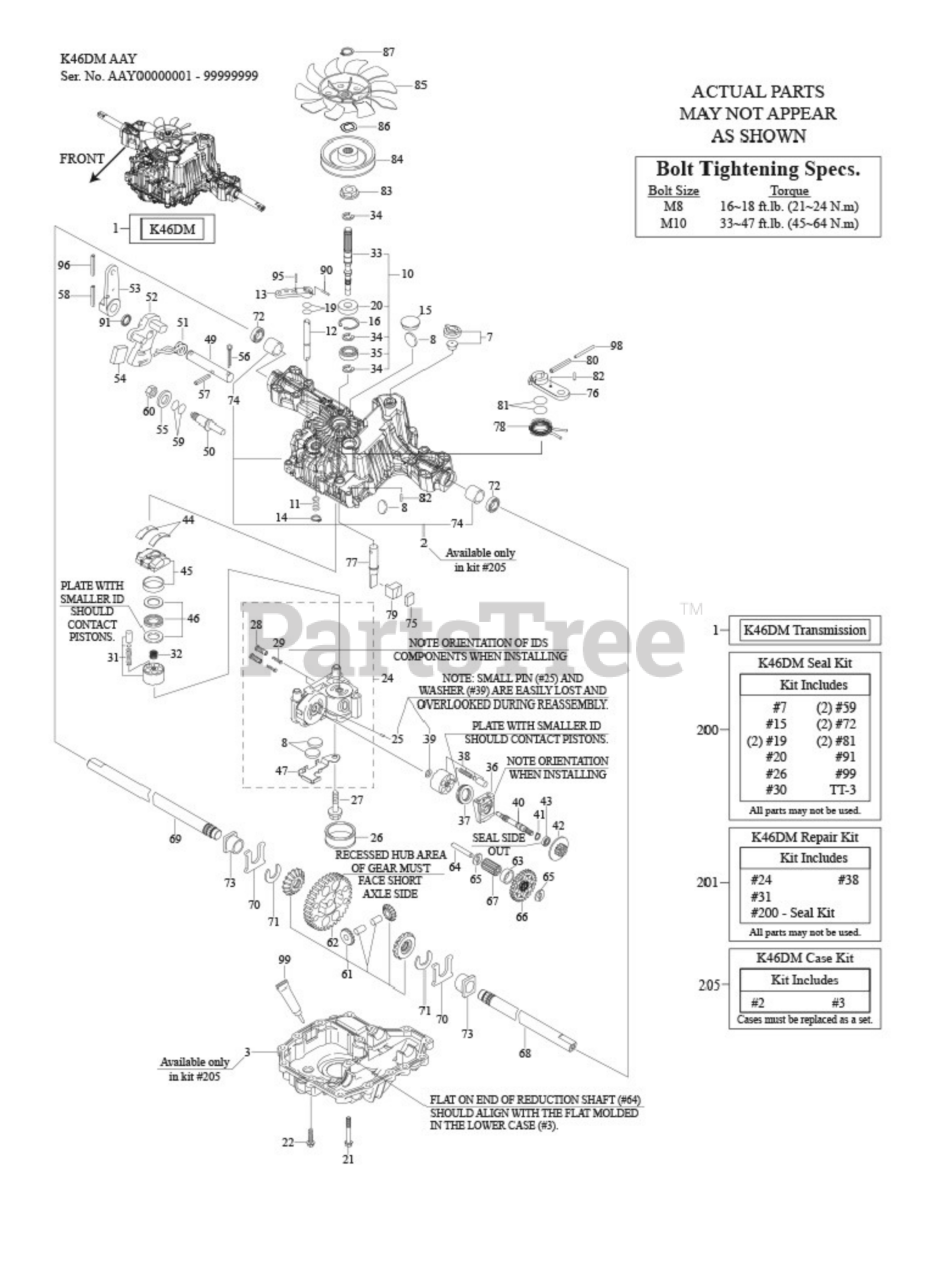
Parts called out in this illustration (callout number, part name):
1	TRANSMISSION ASSEMBLY
3	LOWER HOUSING (Not Available / Order Housing Kit)
7	VALVE ASSEMBLY-VENT
10	SHAFT KIT-PMP W/BRG
21	TAP SCREWPING 8X
22	TAP SCREWPING 8X
24	CENTER CASE KIT / Order Repair Kit
28	VALVE-IDS 1.2
31	CYLINDER BLOCK KIT
32	SPRING-CYL BLOCK
33	SHAFT-PUMP INPUT
35	BALL BEARING
36	HOUSING-MOTOR
37	THRUST BEARING MOTOR
38	CYLINDER BLOCK KIT(MOTOR)
44	BEARING-CRADLE THRUST
45	SWASHPLATE ASSEMBLY
46	BEARING ASSEMBLY-THRUST PM
47	HOLDER-MAGNET
49	SHAFT-CONTROL
51	TORSION SPRING
52	ARM-CONTROL A
53	LEVER-CONTROL F
55	FLAT WASHER 12
56	COTTER PIN 1/8 x .75
57	SPRING PIN 6 x 3
58	ROLL PIN 6 x 4
61	DIFFERENTIAL GEAR ASSEMBLY
62	FINAL GEAR 54T
63	COLLAR-FINAL PINION
64	SHAFT-REDUCTION
65	THRUST WASHER
66	GEAR-REDUCTION 37T
67	FINAL PINION GEAR 10T
68	AXLE SHAFT (LH)
69	AXLE SHAFT (RH)
70	THRUST WASHER
73	BUSHING-FLG AXL
78	SPRING-BRAKE RETUR
79	ACTUATOR-BRAKE
80	SPRING PIN 5 x 3
82	SPRING PIN 4 x 1
83	COLLAR-SPLINE
85	HYDRO FAN BLK
90	SPRING PIN 3 x 2
95	SPRING PIN 3 x 1
96	ROLL PIN 3.5 x 4
98	SPRING PIN 3 x 32
205	UPPER/LOWER HOUSING KIT
